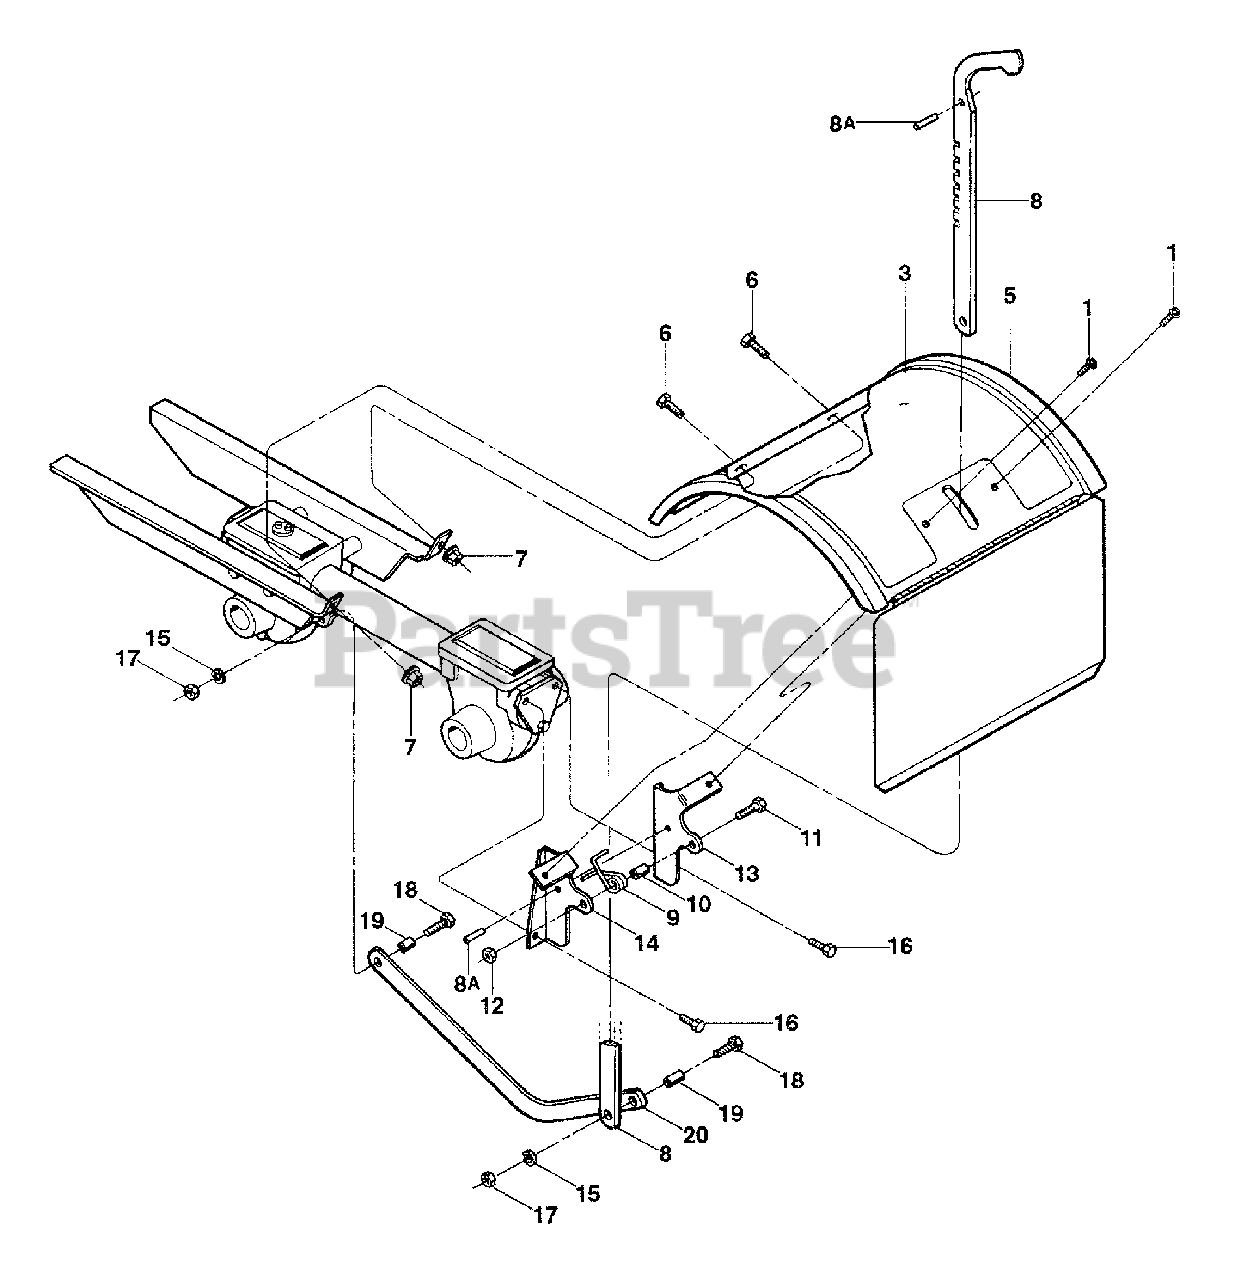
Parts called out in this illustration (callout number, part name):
1	Flange Screw, Self-Tapping, 1/4-20 x 1/2
3	Decal, Hood
5	Tine Hood
6	Hex Screw, 5/16-18 x 1/2
7	Flange Lock Nut, 5/16-18
8	Depth Regulator Lever
8A	Spirol Pin
9	Spring, Depth Regulator
10	Spacer
11	Hex Screw, 1/4-20 x 1
12	Locknut, 1/4-20
13	Hood Bracket, Right Hand
14	Hood Bracket, Left Hand
15	Lockwasher, 5/16
16	Flange Screw, 5/16-18 x 1
17	Hex Nut, 5/16-18
18	Hex Hd. Screw, 5/16-18 x 1-1/4
19	Bushing
20	Drag Bar
